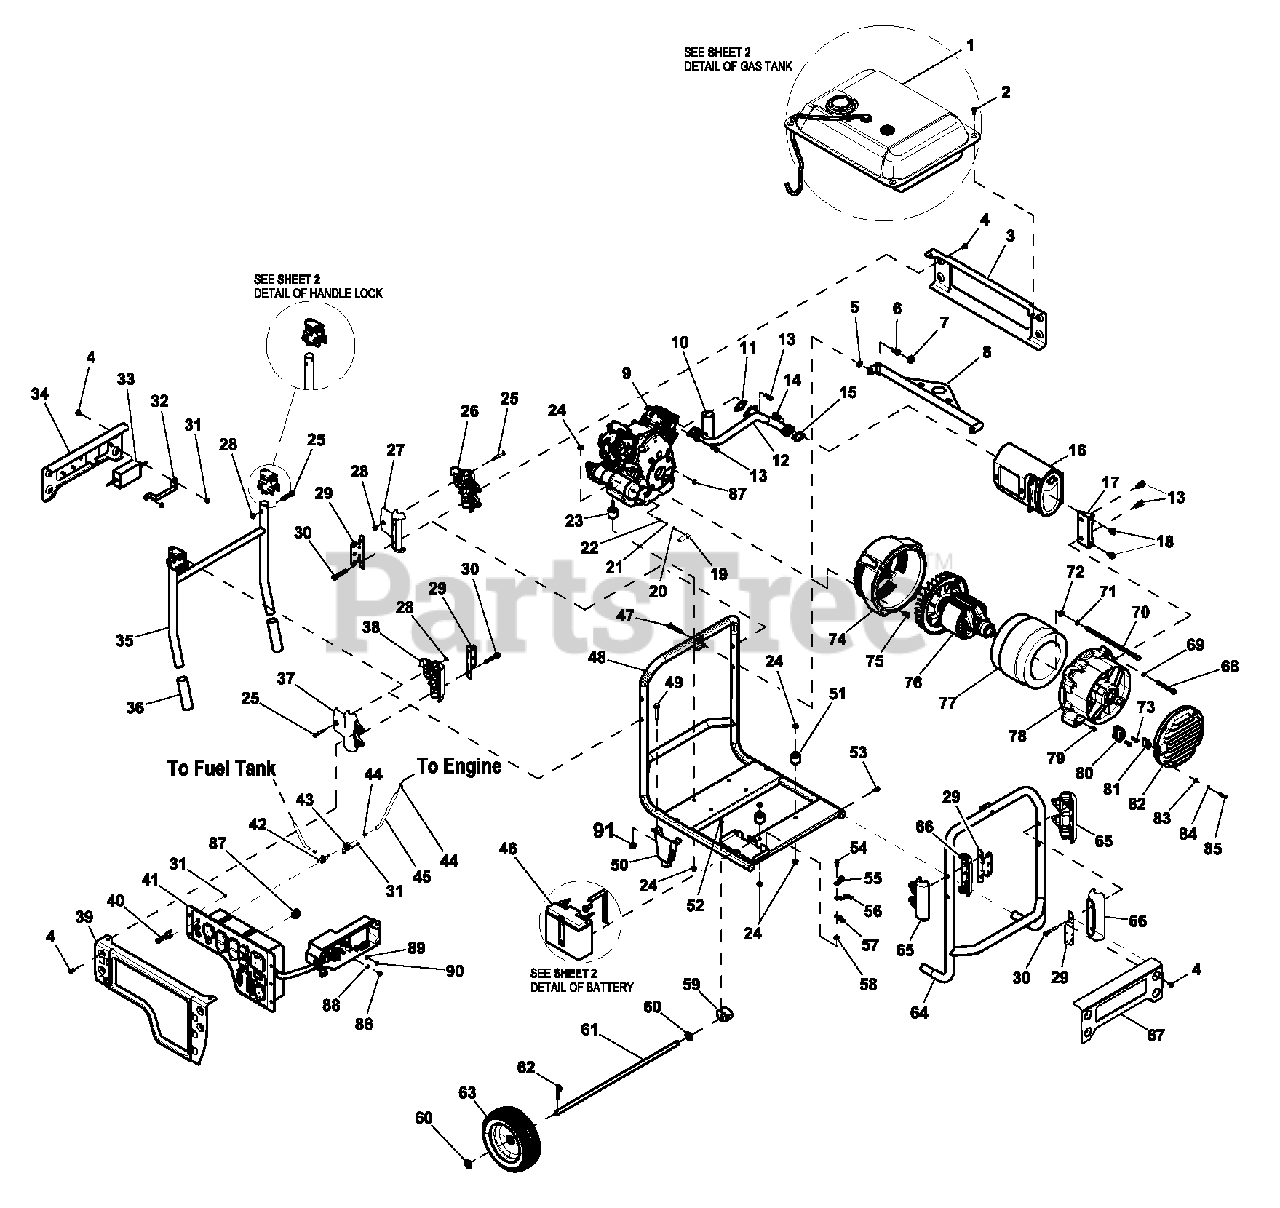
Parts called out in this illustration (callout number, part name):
1	ASSY FUEL TANK 9 GAL XP
2	SCREW TTH M8-1.25 X 20
3	PANEL SIDE XP
4	SCREW SWT 1/4-20 X 5/8 W/W
5	WASHER NYLON .50 X .87 X .06
6	BUSHING,FLANGED HEAD
7	NUT HEX LOCK M8-1.25 NY INS
8	ASSY LIFTING BEAM XP6.5-8
9	ASSY ENGINE 530 PORT
10	TUBE, HEAT RISER 38MM ID
11	GASKET, EXHAUST GT530
12	MANIFOLD GTH530P
13	SCREW SHC M8-1.25 X 20 SEMS
14	SCREW SHC SEMS FLAT M8-1.25X20
15	GASKET,EXHAUST PORT
16	ASSY MUFFLER GTH530
17	MUFFLER MOUNTING BRACKET
18	SCREW HHTT 3/8-16 X 3/4 CZ
19	BOOT, BATTERY CABLE
20	NUT HEX JAM M8 X 1.25 G8 ZYC
21	WASHER LOCK M8 SS
22	WASHER FLAT M8
23	VIB MNT 1.38X1.0X5/16-18 MXM
24	NUT HEX FLANGE WHIZ 5/16-18
25	SCREW SHSH M8-1.25 X 40
26	CORNER HANDLE SUPT-LFT OUTER
27	CORNER HANDLE SUPT-LFT INNER
28	NUT HEX M8-1.25 G8 CLEAR ZINC
29	BRACKET END PANEL
30	SCREW HHFC M8-1.25X60 C8.8 ZP
31	NUT HEX FL WHIZ M6-1.0
32	BRKT HOLD DOWN BATT CHRGR
33	BATTERY CHARGER 13.4 VDC 2.5A
34	WELD END PANEL XP
35	HANDLE FOLDING 2008 XP-SERIES
36	GRIP HANDLE FOAM
37	CORNER HANDLE SUPT-RT OUTER
38	CORNER HANDLE SUPT-RT INNER
39	WELD PANEL SIDE C-PNL XP
40	ASSY 12VDC POWER JACK XP
41	ASSY C-PNL XP10KW
42	VALVE, FUEL SHUT OFF
43	MTG FUEL VALVE RETAINER
44	CLAMP HOSE BAND .41
45	FUEL HOSE 160 MM LONG
46	BATTERY 12V18AH SEALED
47	CURVED HEAD M8-1.25 X 60MM LNG
48	WELD CRADLE ENGINE END
49	SCREW HHFC M8-1.25 X 45
50	FOOT ASSY XP
51	VIB MNT .63 X .63 5/16-18
52	SCREW HHFC M6-1X50 8.8 W/PATCH
53	SCREW HHSD 1/4-14 X 7/8 BZ
54	SCREW HHTT M6-1.0 X 20 ZINC
55	LUG SLDLSS #2-#8 X 17/64 CU
56	WIRE ASSY,PNL GND/FR GND,XG10
57	GRND WIRE PORT BRG CARR-FRAME
58	WASHER LOCK SPECIAL 1/4"
59	AXLE MNT
60	WASHER FLAT 5/8 ZINC
61	AXLE 15.87 DIA X 684 CLR ZINC
62	COTTER HAIRPIN 2.56 X .80
63	10" WHEEL OFFSET HUB
64	WELD CRADLE ALT END
65	CORNER SUPPORT - OUTER XP PORT
66	CORNER SUPPORT - INNER XP PORT
67	WELD END PANEL XP
68	SCREW HHC M8-1.25 X 110 C8.8
69	WASHER LOCK M8-5/16
70	SCREW IHHC 3/8-24 X 10.75 G8
71	WASHER LOCK 3/8
72	WASHER FLAT 3/8-M10 ZINC
73	SCREW HHTT M5-0.8 X 16
74	ADAPTOR HOUSING, W/O TOP SLOTS
75	SCREW FHSC 3/8-16 X 3/4 W/LOCK
76	RTR-102-10.0AD1 CHI XG CANLESS
77	STR ASSY 10KW 10" PORT W/OUT FAN
78	BEARING CARRIER, 10IN ALT
79	SCREW HHTT M6-1.0 X 12 ZINC
80	ASSEMBLY, BRUSH HOLDER
81	GROMMET WIRE SLEEVE
82	END COVER, 10IN ALTERNATOR
83	WASHER FLAT #10 ZINC
84	WASHER LOCK #10
85	SCREW PPHM M5-0.8 X 30 ZINC
86	NUT HEX LOCK M5-0.8 NYINS ZINC
87	CLIP SNAP-IN WIRE MANAGEMENT
88	WASHER FLAT M5
89	WASHER FLAT M6
90	NUT HEX LOCK M6-1 NY INS
91	NUT HEX FL WHIZ M8-1.25
